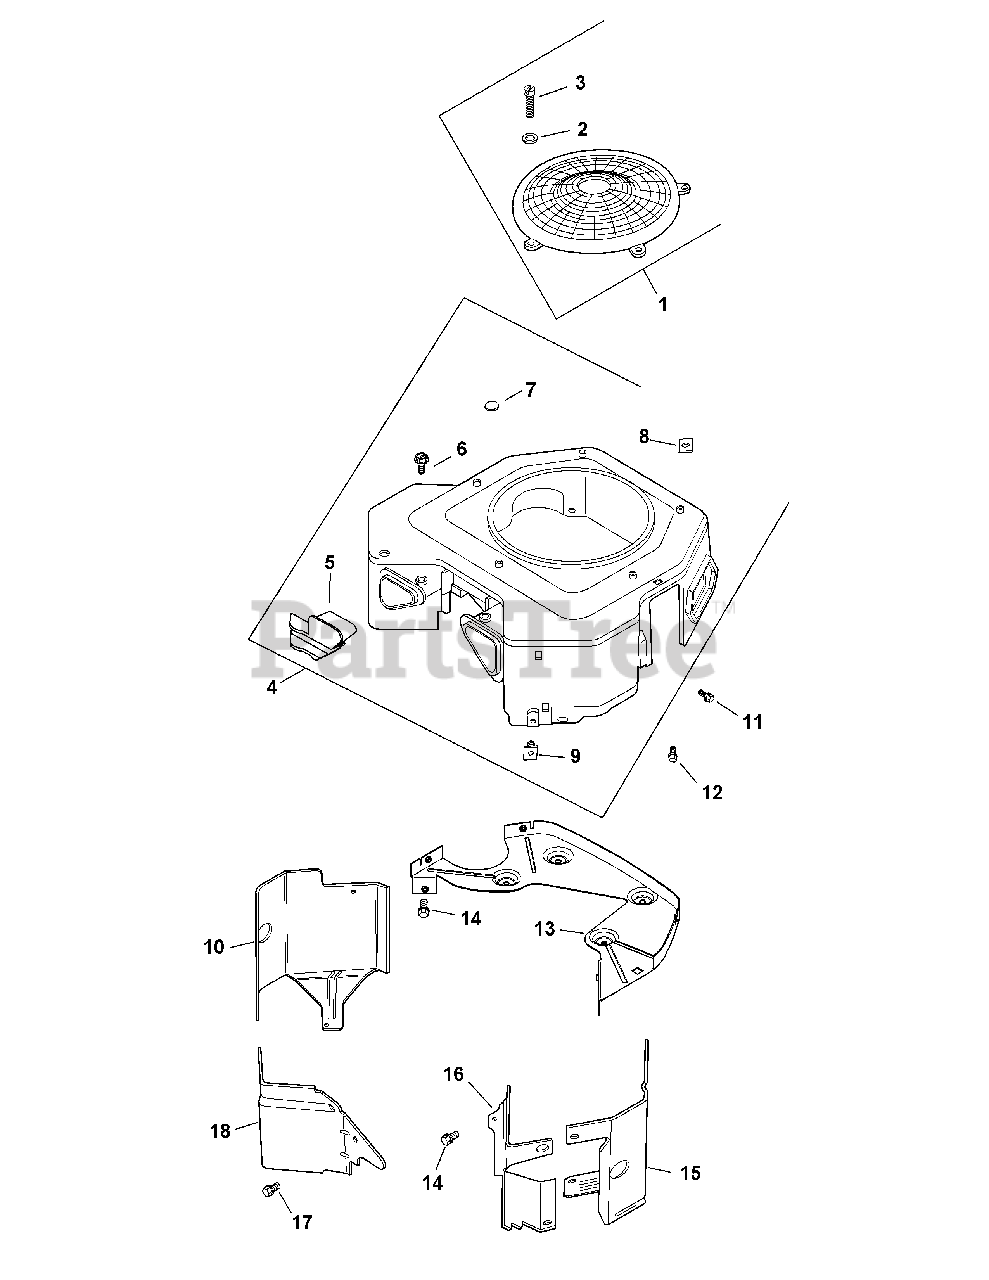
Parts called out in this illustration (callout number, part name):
1	Kit, Guard
2	Washer, Flat 7/32
3	Screw, Lbd Skt Pan M5x0.8x10
4	Kit Blower Housing Assembly
5	Cover, Blower Housing-Molded
6	Screw, WSH HD Tap #8-18 x 1/2"
7	Plug, Button 9/16
10	Kit, Cyl Barrel - #1 Side
11	Screw, Flg Thd Frm M5x0.8x16
12	Screw, Flg Thd Frm M5x0.8x20
13	Kit, Backing Plate (Inc. M-545016-S)
14	Screw, Flg Thd Frm M6x1.0x16
15	Kit, Cyl Baffle - #2 Side
16	Baffle, Valley #2 Side
17	Screw, Flg Thd Frm M5x0.8x10
18	Baffle, Valley #1 Side
